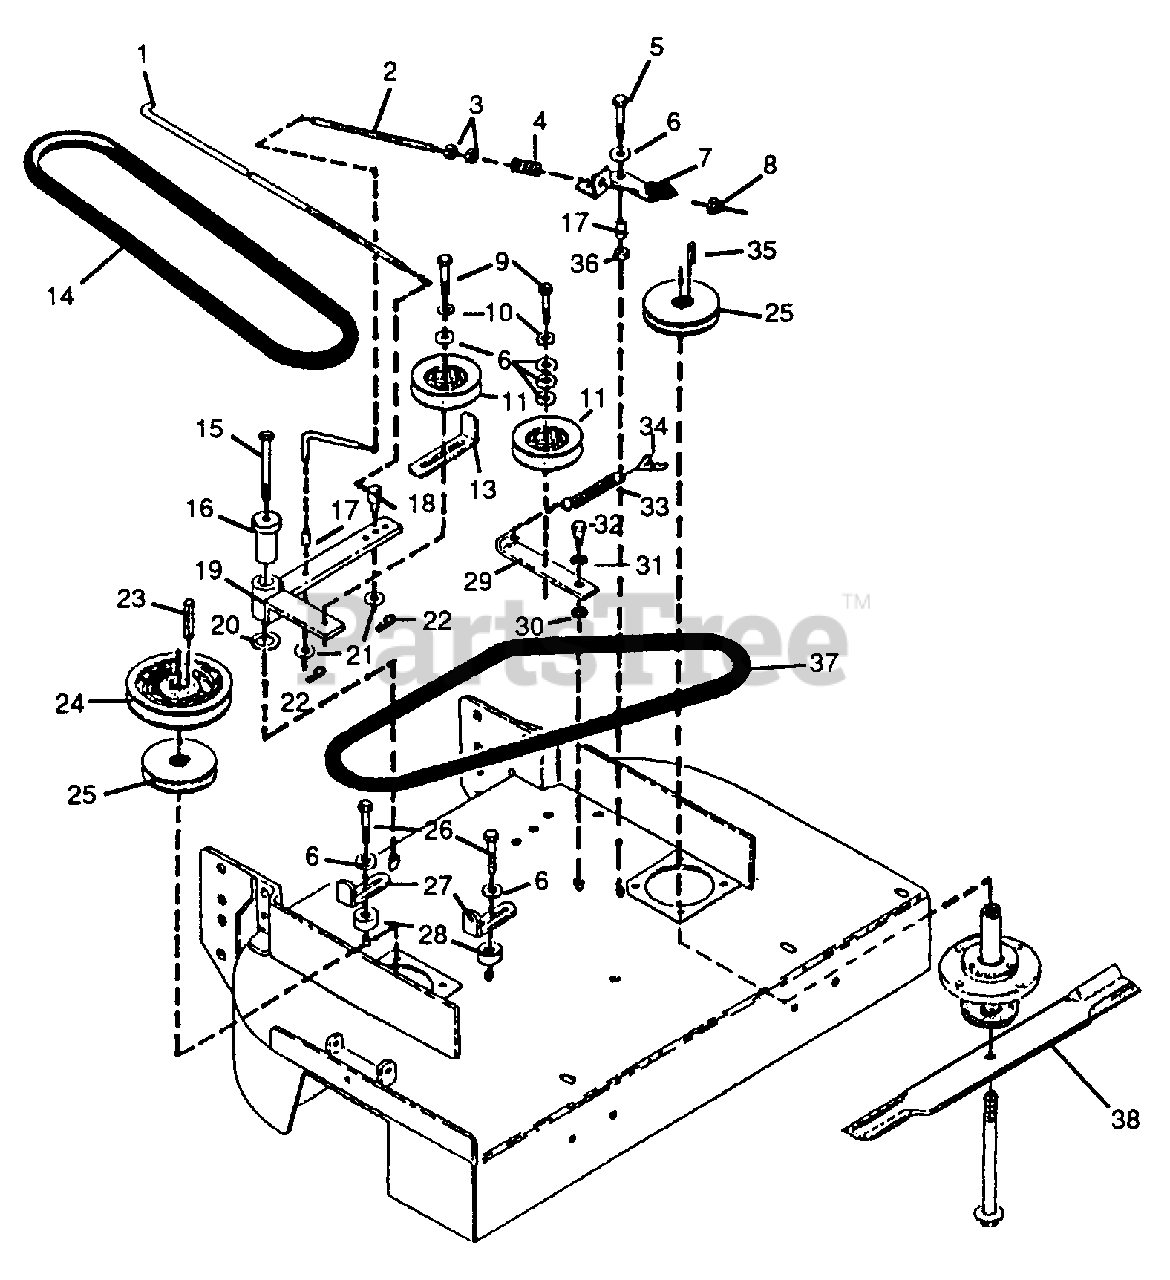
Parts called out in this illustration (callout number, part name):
1	Rod, Blade Engagement
2	Rod, Brade Brake
3	5/16 -18 Flange Nut
4	Spring
5	3/8 -16 x 2 Hex. Hd. Cap Screw
6	3/8- FlatWasher
7	Brake LeverAssembly
8	5/16 -18 Flex Lock Nut
9	3/8 -16 x 1-1/2' Hex. Hd. Cap Screw
10	3/8- Spring Lock Washer
11	Idler Pulley W/Bushing
13	Beltguide
14	Belt, Engine - Blade
15	3/8' -16 x 3- Hex. Hd. Cap Screw
16	Pivot Bushing
17	Spacer
18	Swivel
19	Idler Arm
20	1" Machinery Bushing
21	5/16 Flat Washer
22	#13 Hair Pin
24	Pulley
25	Pulley
26	3/8 -16 x 1-1/4 Hex. Hd. Cap Screw
27	Beltguide
28	Spacer
29	Idler Arm
30	Snap Bushing
31	Bellville Washer
32	Shoulder Bolt
33	Spring
36	3/8 -16 Flange Nut
37	Belt, Blade- Blade
38	18 Blade, High-Lift
